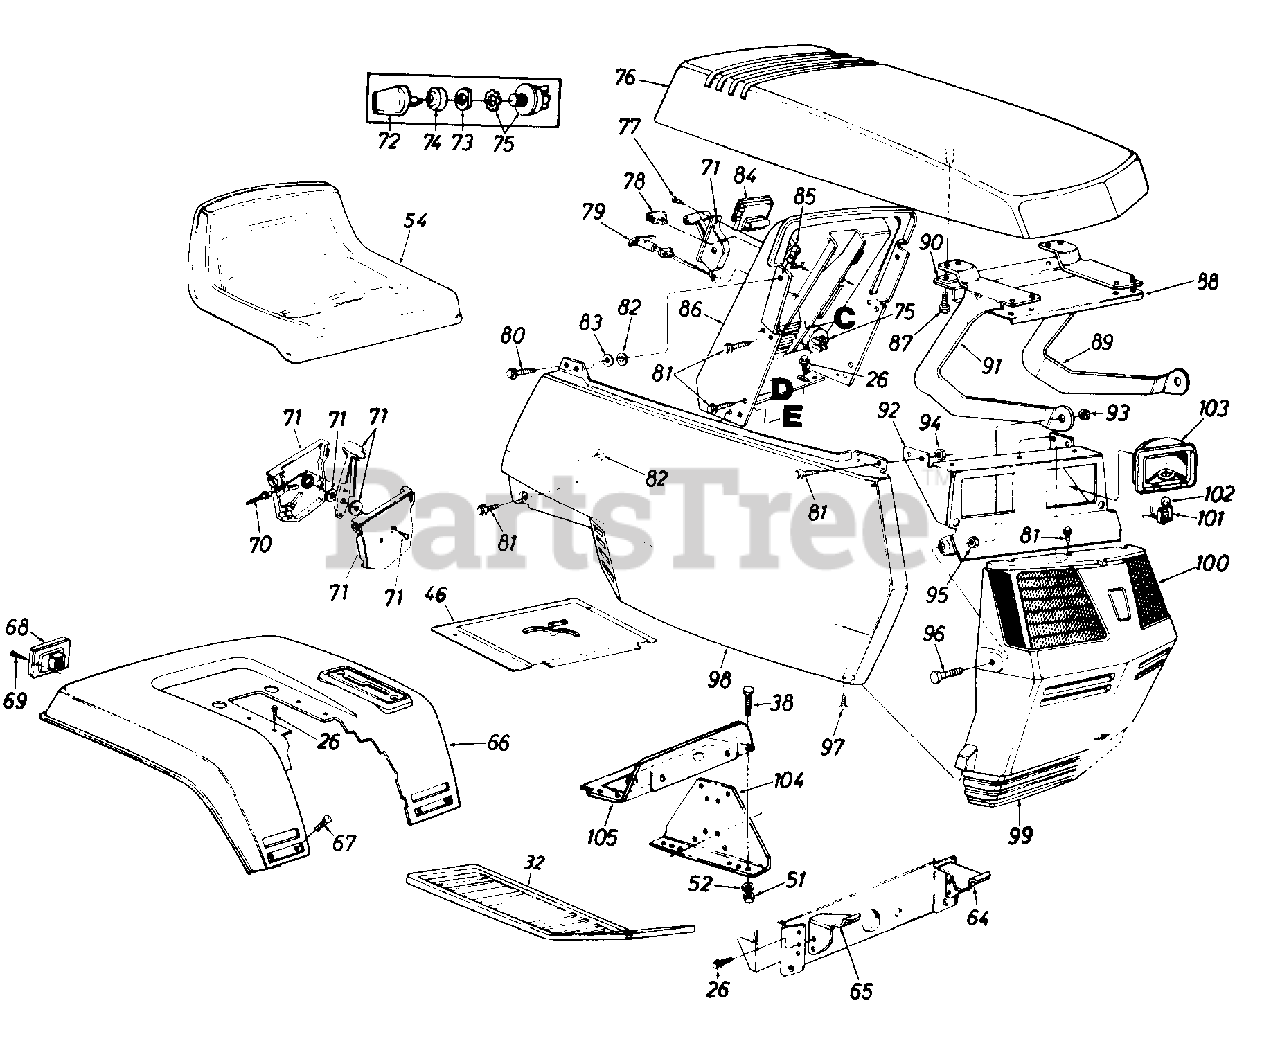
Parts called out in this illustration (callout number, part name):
26	Hex Wash. Hd. AB-Tap Scr. 5/16 x .75" Lg.
32	Rubber Foot Pad L.H.
38	Hex Bolt 5/16-18 x .75" Lg.
46	Shift Cover
51	Hex Nut 5/16-18 Thd.
52	L-Wash. 5/16" I.D.
54	Seat
64	Grille Mount Brkt. L.H.
65	Grille Mount Brkt. R.H.
68	Taillight
69	Truss Hd. AB-Tap Scr. #6 x .62" Lg.
70	Throttle Wire 26" Lg.
71	Throttle Control Box As'y.
72	Ignition Key
73	Ignition Switch Nut
74	Ignition Switch Cap
75	Ignition Switch
78	Light Switch
79	Chute Control 38" LD.
80	Hex Wash. Hd. Tap Scr. 1/4 x .75" Lg.
81	Hex Tap Scr. 1/4-20 x .5" Lg.
82	Push Nut Fastener
83	Fl-Wash. .27" I.D. x 948"
84	Ammeter
85	Speed Nut 1/4-20 Thd.
86	Dash Panel
87	Hex Wash. Hd. B-Tap Scr. 1/4 x .62" Lg.
88	Hood Reinforcement
89	Hood Hinge L.H.
94	Hex L-Nut 1/4-20 Thd.
95	Hex Jam Nut 5/16-18 Thd.
96	Hex Bolt 5/16-18 x 7/8" Lg.
97	Truss Mach. B-Tap Scr. #10 x .5" Lg.
98	Side Cover R.H.
99	Grille
100	Lens L.H.
101	Twist Lock Lamp Socket
102	Lamp
103	Headlight Housing
104	Dash Support Brkt.
105	Gas Tank Support Brkt.
